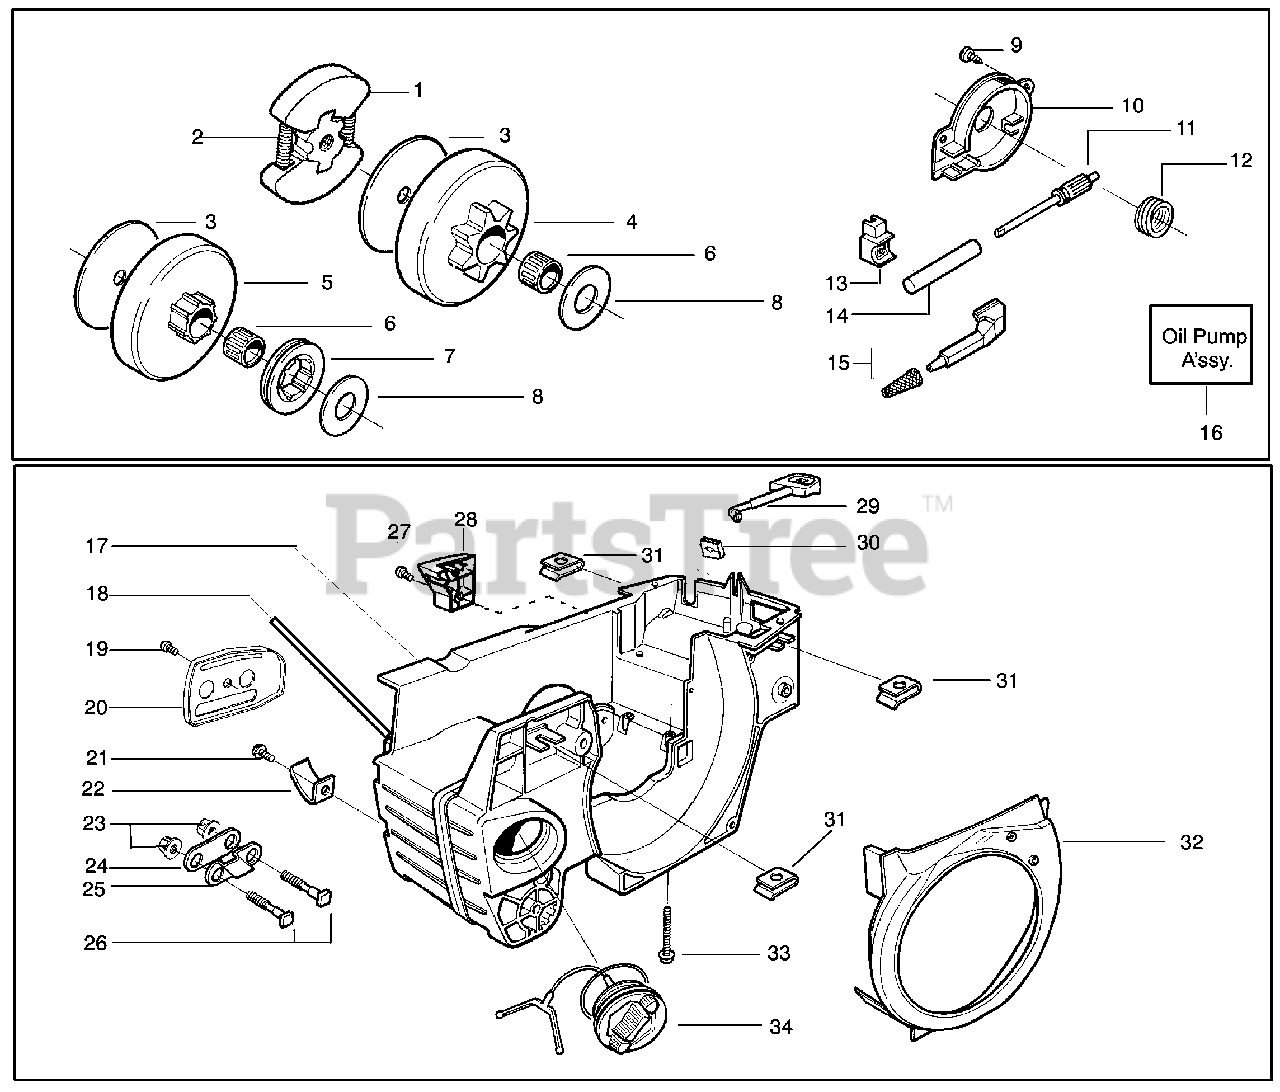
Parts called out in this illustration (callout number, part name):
1	Clutch Assembly
2	Spring - Clutch
3	Clutch Washer
4	Clutch Drum w/Bearing Ass'y. (3/8x6 spur)
5	Drum, Adapt. & Bearing Kit
6	Clutch Bearing
7	Rim-Floating (.325)
8	Thrust Washer
10	Oil Pump Housing
11	Plunger & Gear Assembly
12	Oil Pump Worm
13	Oil Seal
14	Oil Pump Barrel
15	Oil Pick-Up and Screen Assembly
16	Oil Pump Assembly
17	Kit - Chassis Ass'y.
18	Tube-Oil Vent
19	Screw
22	Chain Catcher
25	Bar Stud Plate
29	Choke Lever
31	Type "U" Speed Nut
32	Baffle Plate
34	Assy.- Oil Tank Cap
